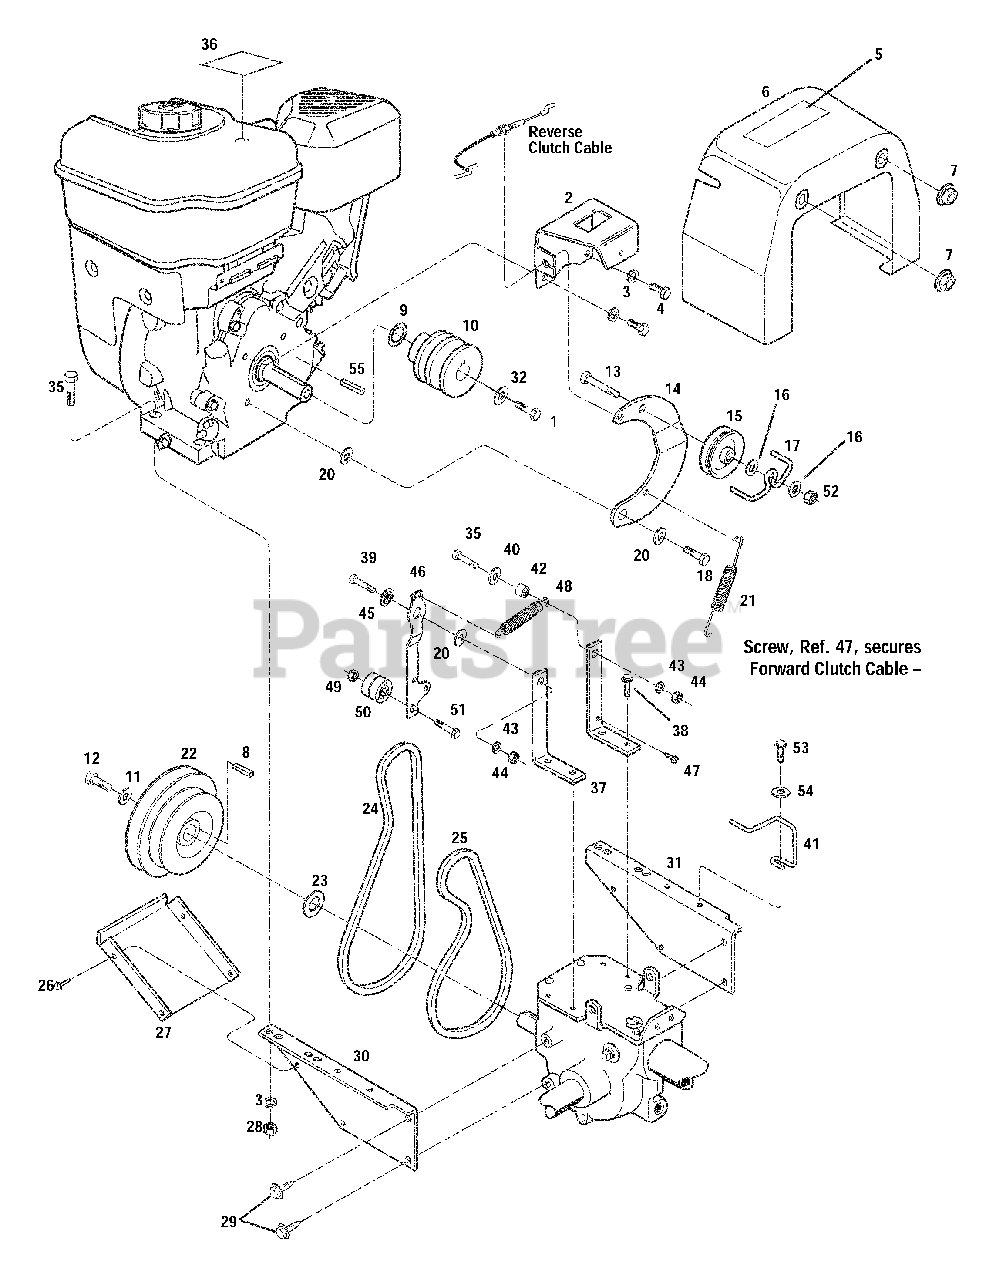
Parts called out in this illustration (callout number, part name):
1	Screw, 3/8-24 x 1.75
2	Bracket, Clutch Cable
3	Lockwasher-5/16
4	Hex Hd. Screw, 5/16-24 x 1/2
5	Decal, Hot Surfaces/Belt Warning
6	Cover
7	Flange Lock Nut, 5/16-18
8	Key, 3/16 x 1-1/2
9	Shim
10	Pulley, Engine Drive
11	Belleville Washer
12	Hex Hd. Screw, 5/16-24 x 1-1/8
13	Hex Hd. Screw, 5/16-18 x 2
14	Reverse Idler Arm
15	Pulley, Reverse Idler
16	Flat Washer, 5/16
17	Belt Guide, Wire Formed
18	Hex Head Screw, 5/16-24 x 1
19	Washer, Shoulder
20	Washer, Flat, 1-1/8
21	Spring, Reverse Return
22	Transmission Pulley
23	Support Washer
24	Reverse Clutch Belt
25	Forward Clutch Belt
26	Self-tapping Screw, #10-32 x 1/2,
27	Guard, Belts/Pulleys
28	Hex Nut, 5/16-18
29	Hex Flange Screw, 5/16-18 x 3/4
30	Engine Support Bracket, left side
31	Engine Support Bracket, right side
32	Bell Washer
35	Hex Hd. Screw, 5/16-18 x 2-1/4
36	Decal, Stabilization
37	Mounting Bar
38	Hex Flange Screw, 5/16-18 x 1
39	Hex Hd. Screw, 5/16-18 x 1-1/2
40	Flat Washer, 5/16'
41	Belt Guide, Pony
42	Pivot Bushing
43	Lockwasher, 5/16
44	Hex Nut, 5/16-18
45	Washer, Shoulder
46	Idler Arm, Forward Tiller Direction
47	Screw, self tapping, #10-24
48	Spring
49	Hex Locknut, 5/16-18
50	Idler Pulley, Forward
51	Screw, 3/8-16 x 1-3/4
52	Hex Lock Nut, 5/16-18
53	Screw, 1/4-20 x 3/4
54	Flat Washer-1/4
55	Key, .188 x 1.75
